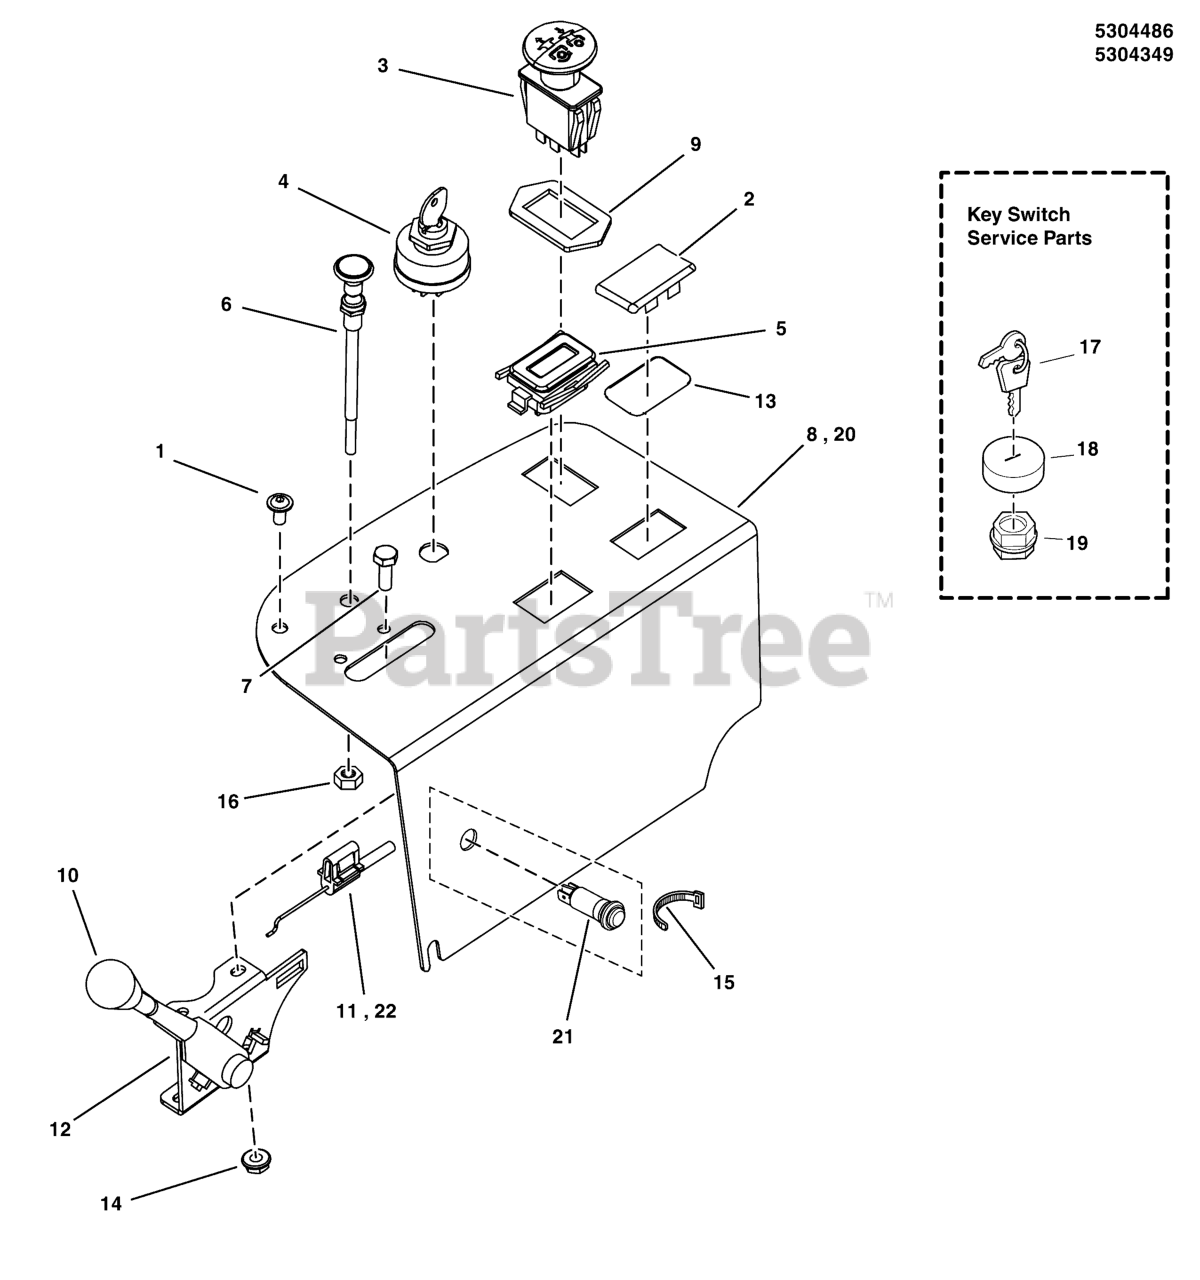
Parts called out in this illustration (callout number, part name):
1	SCREW, ALLEN HEAD 1/4-20X.500 ZINC PHOS
2	PLUG, .820X1.44 HOLE, BLACK PLASTIC
3	SWITCH, BLADE ENGAGEMENT
4	SWITCH, IGNITION, 6 POST
5	HOUR METER, ASSEMBLE
6	CABLE, CHOKE CONTROL, 51" (Z)
7	SCREW, #10-24 X 3/4" ROUND PHILLIPS
8	PANEL, Control - Black
9	RING, SWITCH RETAINER
10	THROTTLE CONTROL HANDLE/KNOB
11	CABLE, THROTTLE, 42"
12	LEVER, THROTTLE CONTROL, HEAVY-DUTY
13	O-RING, 7/8" ID X 1/16" W
14	NUT, Hex, Nylon Lock, #10-24
15	TIE, SELF-LOCKING, 12"
16	NUT, 3/8-24 HEX (SV)
17	KEY, IGNITION MOLDED SET
18	COVER, PLASTIC, SNAP ON
19	PLASTIC NUT
20	PANEL, CONTROL, IS2100/3200 - BLK
21	LIGHT, INDICATOR, PANEL, LED, RED
22	CABLE, THROTTLE, 52"
